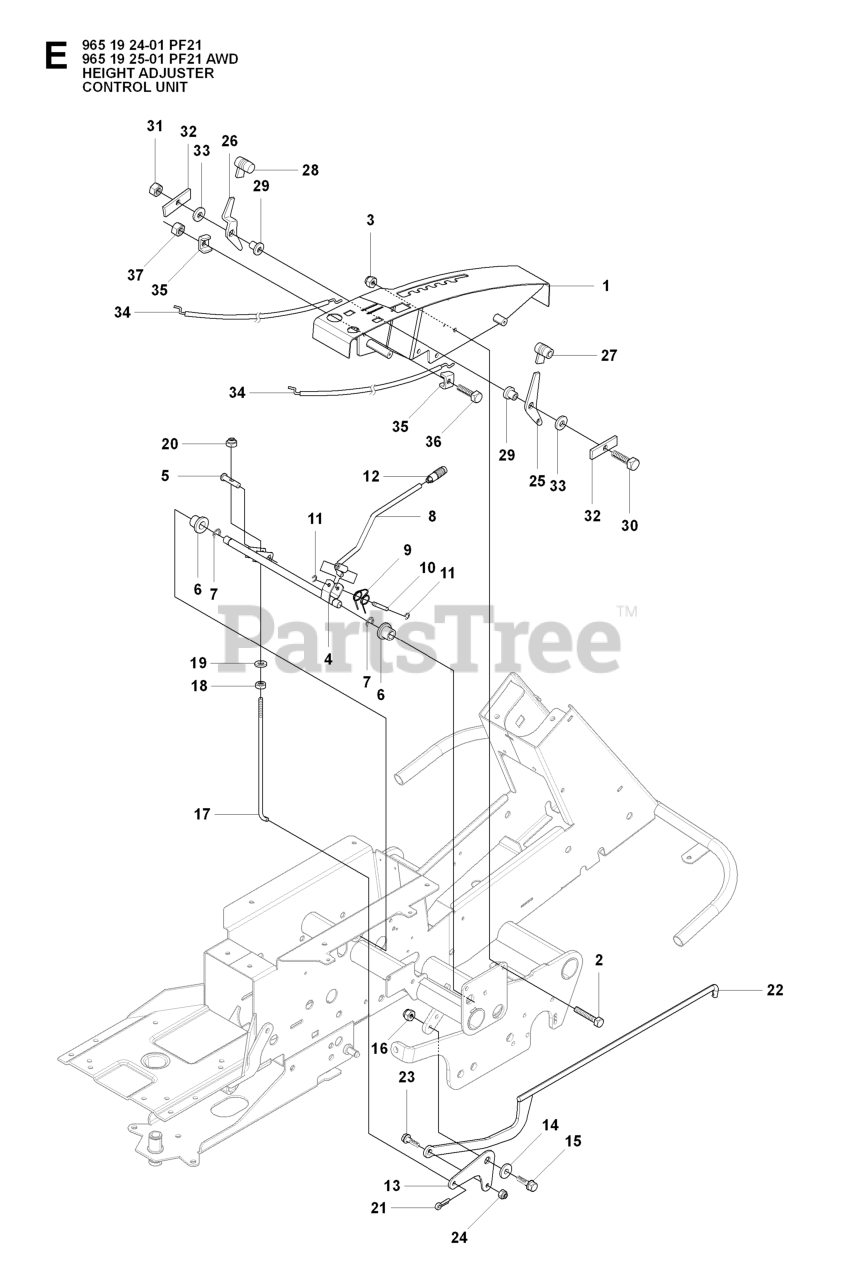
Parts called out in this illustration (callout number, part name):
3	LOCKNUT M8
6	BUSHING
9	HAIR PIN SPRING
12	GEAR STICK KNOB
14	WASHER
16	LOCKNUT M6
18	NUT
19	WASHER
20	LOCKNUT M8
24	NUT
30	SCREW M6S 6X30
31	LOCKNUT M6
33	SPRINGWASHER
37	LOCKNUT M5
